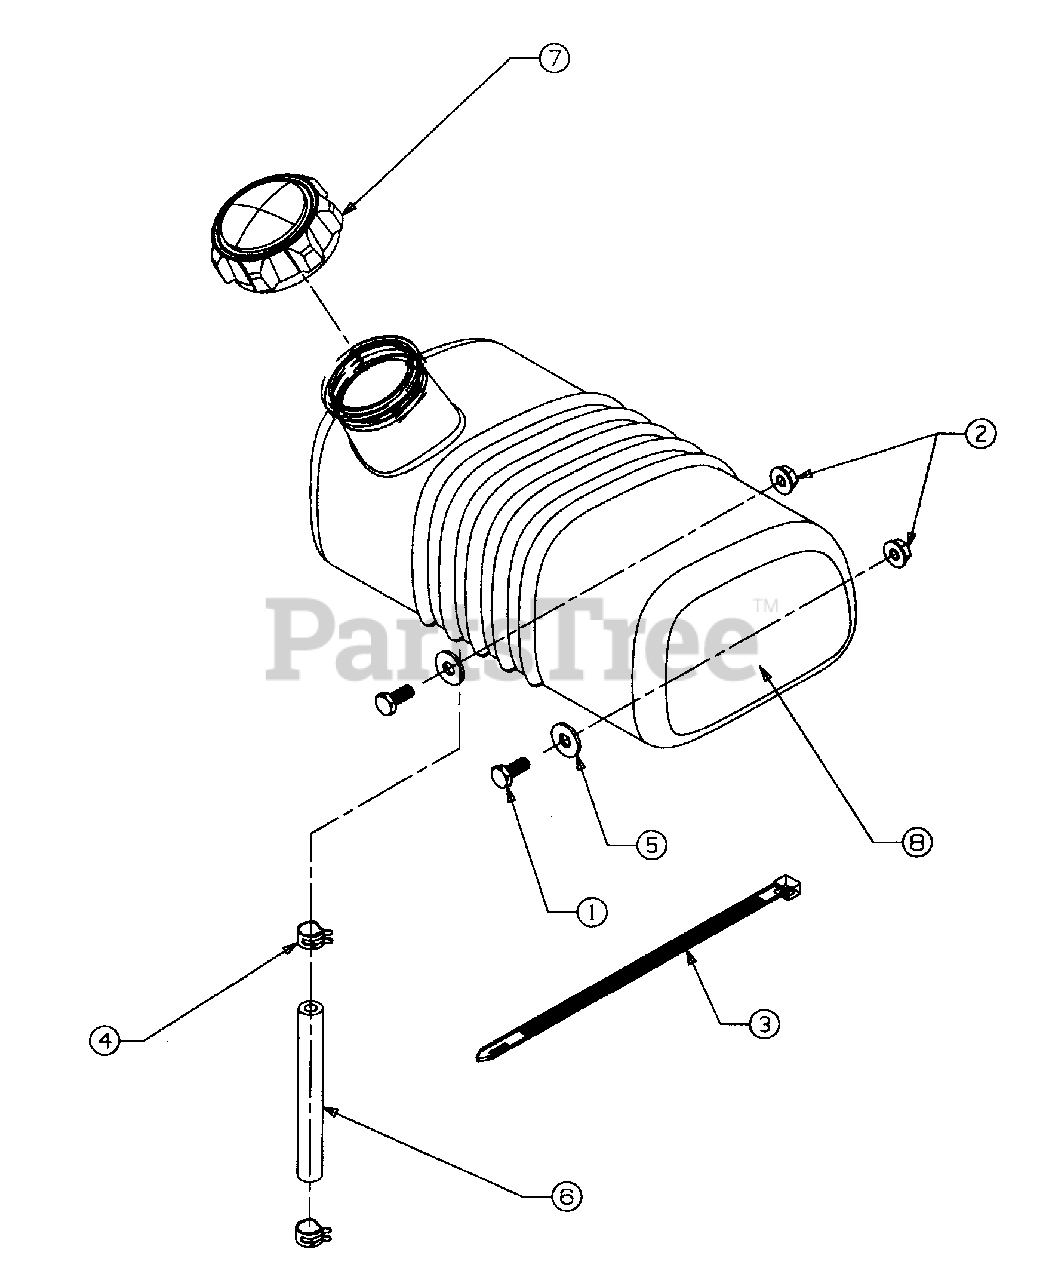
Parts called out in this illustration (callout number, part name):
1	SCREW-HEX
2	NUT-HEX LOCK FLANGE
3	CABLE TIE
4	CLAMP-HOSE
5	WASHER-FLAT
6	HOSE-FUEL LINE 12"
7	CAP-FUEL
8	TANK-FUEL 1 GALLON
